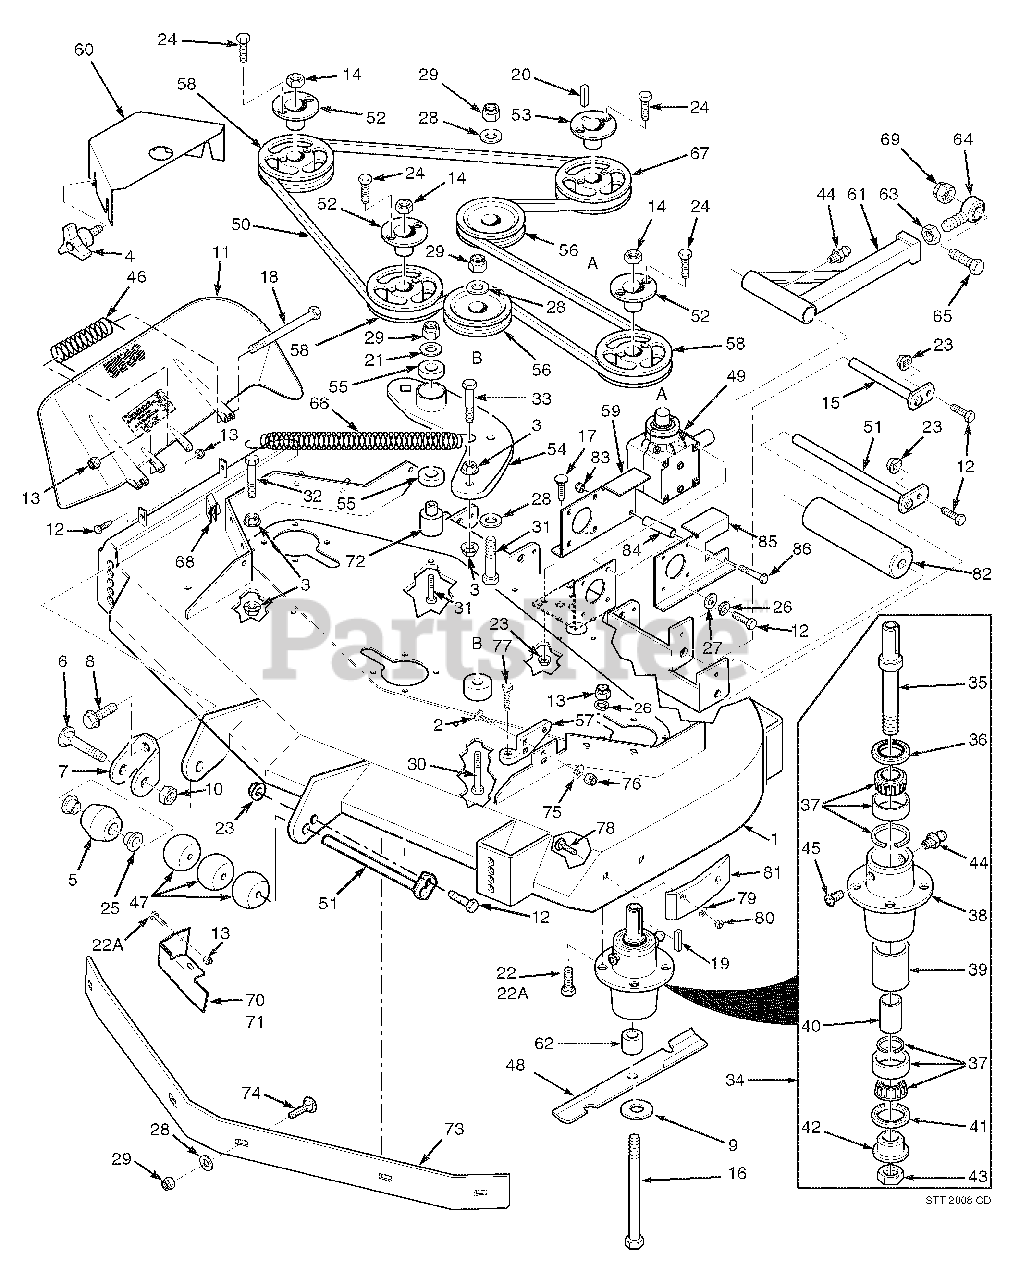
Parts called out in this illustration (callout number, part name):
1	Cutter Deck Velocity Plus
2	Bolt, Carriage 7/16-14 x 1-1/4"
3	Nut, Hex Serrated Flange 3/8-16
4	Wing nut, 3/8-16
5	Anti-Scalp Wheel
6	Bolt, Carriage 3/8-16 x 4"
7	Anti-Scalp Wheel Bracket
8	Bolt, Hex Serrated Flange 3/8-16 x 1"
9	Flatwasher, 5/8" Hardened
10	Locknut, 3/8-16 Center Lock
11	Discharge Chute
12	Bolt, Hex Head 5/16-18 x 1-3/4" - Front
13	Nut, Hex Elastic Stop 5/16-18 Grade 8
14	Nut, 5/8-11 UNC
15	Push Arm Shaft
16	Bolt, Hex Head 5/8-11 x 9-1/2"
17	Bolt, Carriage 5/16-18 x 3/4"
18	Bolt, Hex Head 5/16-18 x 4-1/2"
19	Key, 1/4 x 1/4 x 2"
20	Key, 1/4 x 1/4 x 1-1/4"
21	Flatwasher,3/8-.39 x .938 x .105 HD
22	Bolt, Hex Head 5/16-18 x 1-3/4"
23	Nut, Hex Serrated Flange 5/16-18
24	Bolt, Hex Head 1/4-20 x 1" Grade 8
25	Bushing, .376 I.D. Oilite
26	Lockwasher, 5/16"
27	Flatwasher, 5/16"
28	Flatwasher, 3/8"
29	Nut, Hex Elastic Stop 3/8-16
30	Bolt, Hex Head 3/8-16 x 3-1/4"
31	Bolt, Hex Head 3/8-16 x 3"
32	Bolt, Hex Head 3/8-16 x 1-1/2"
33	Bolt, Hex Head 3/8-16 x 1-1/2" Grade 8
34	Spindle Assembly
35	Spindle Shaft
36	Seal, Top
37	Bearing Assembly
38	Spindle Housing
39	Spacer, Outside
40	Spacer, Inside
41	Seal, Bottom
42	Spindle Bushing, Bottom
43	Nut , Spec ial 1 -1/ 1 6 - 1 8
44	Grease Fitting
45	Relief Fitting, Tapered Spindle
46	Spring, Discharge Chute
47	Wheel, Anti-Scalp
48	Cutter Blade, 21"
49	Gearbox Assembly, Deck Drive
50	Belt, Cutter Deck Drive
51	Roller Shaft
52	Tapered Hub, 1-1/8" Bore
53	Tapered Hub, 1" Bore
54	Idler Arm, Cutter Deck
55	Bearings, Ball
56	Pulley, Idler
57	Lever Assembly, Deck Level
58	Pulley, 6.35 O.D.
59	Mounting Plate, RH Gearbox
60	Belt, Cover
61	Pusharm
62	Spacer, Spindle Bottom
63	Nut, Hex Head 5/8-18 UNF
64	Rod End, 5/8" Male RH Thread
65	Bolt, Hex Head 5/8-11 x 4-1/2"
66	Spring, Cutter Deck
67	Pulley, 6.75 O.D.
68	U-Nut, 3/8-16
69	Nut, Hex Elastic Stop 5/8-11
70	Discharge Baffle 52V
72	Pivot, Idler - Short
73	Baffle, Custom Cut 61V
74	Bolt, Carriage 3/8-16 x 1"
75	Flatwasher, 7/16-.500 x 1.25 x .083
76	Nut, Elastic Stop 7/16-14
77	Bolt, Deck Adjust
78	Bolt, Carraige 5/16-18 x 3/4"
79	Flatwasher, 5/16"
80	Nut, Center Lock 5/16-18
81	Wear Pad
82	Wheel, Anti-Scalp
83	Nut, Elastic Stop 5/16-18
84	Spacer, Gearbox Mount
85	Mounting Plate, LH Gearbox
86	Bolt, Hex Head 5/16-18 x 4-3/4"
